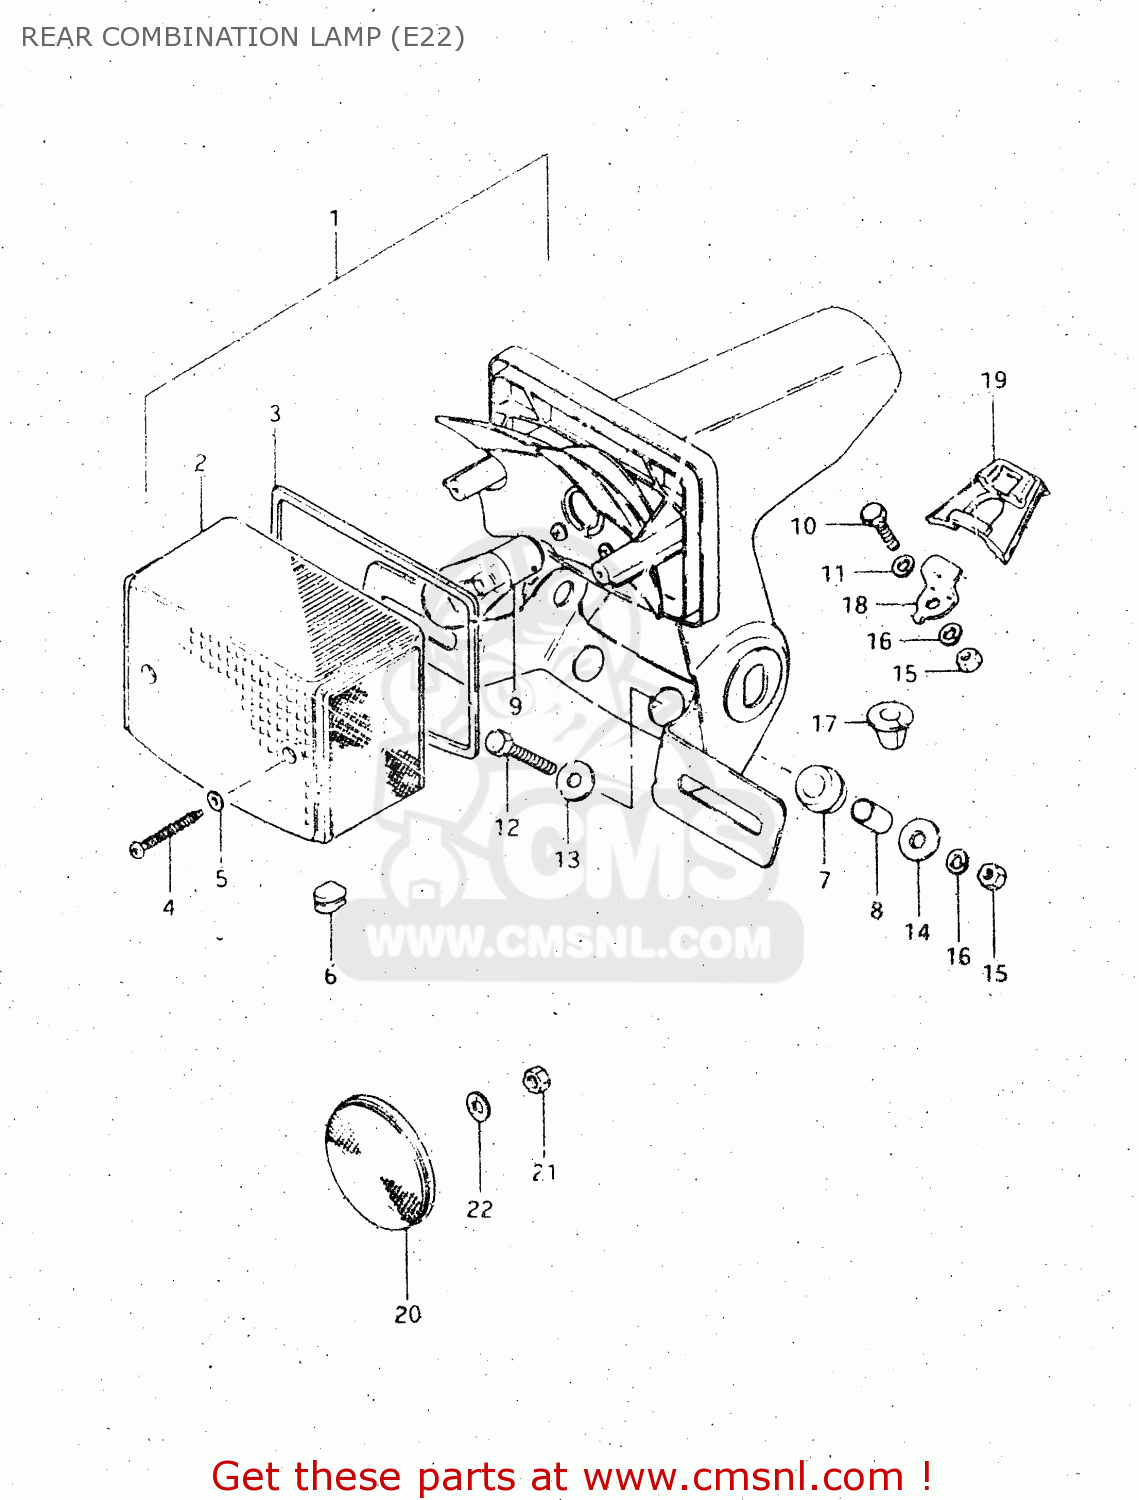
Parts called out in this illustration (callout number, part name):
1	LAMP ASSY, TAIL
2	LENS,RR COMBINATION
3	GASKET (NAS)
4	SCREW
5	GASKET (NAS)
6	GROMMET,REAR COMBINATION LAMP
7	CUSHION,REAR COMBINATION LAMP
8	SPACER
9	BULB (6V,21/5W)
10	BOLT
11	LOCK WASHER
12	BOLT
13	WASHER (6.5X20X1.2)
14	WASHER
15	NUT
16	WASHER
17	GROMMET
18	PLATE
19	CUSHION
20	REFLECTOR,REFLEX
21	NUT
22	WASHER
